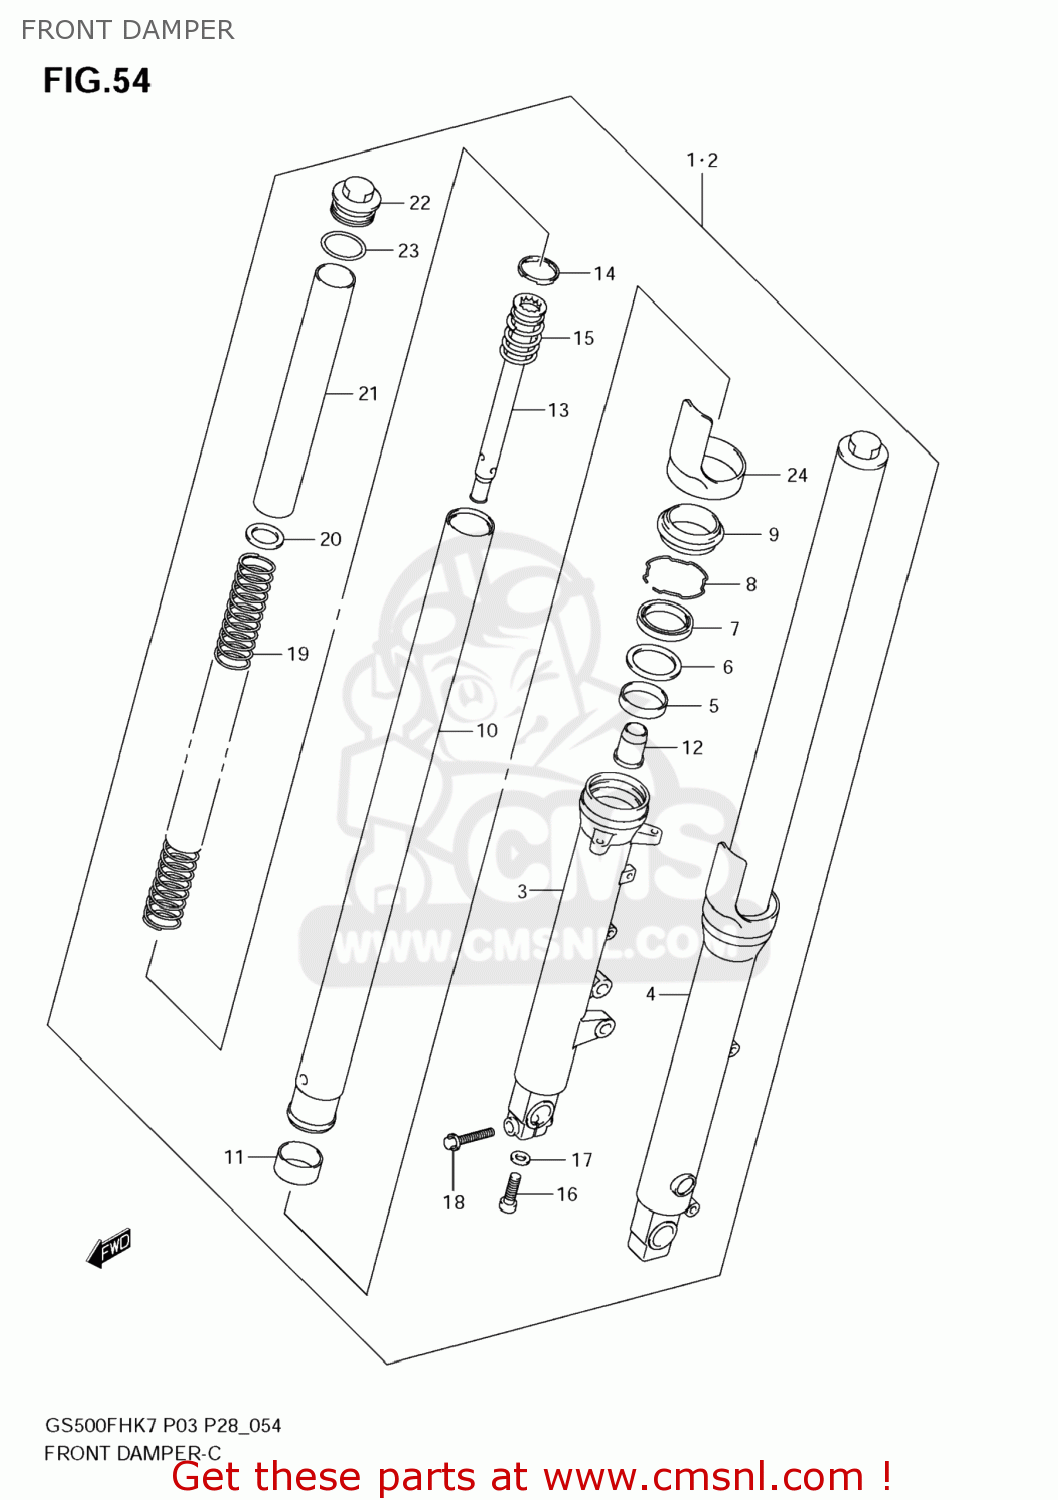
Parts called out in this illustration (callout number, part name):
1	DAMPER ASSY RH
2	DAMPER ASSY LH
3	TUBE, OUTER RH
4	TUBE, OUTER LH
5	METAL, SLIDE
6	WASHER
7	SEAL, OIL
8	RING, SNAP
9	SEAL, DUST
10	TUBE, INNER
11	PISTON
12	PIECE, OIL LOC
13	CYLINDER
14	RING, PISTON
15	SPRING, REBOUN
16	BOLT
17	GASKET (NAS)
18	BOLT RH
19	SPRING, MAIN
20	WASHER, SPRING
21	SPACER
22	CAP
23	O RING
24	PROTECTOR
